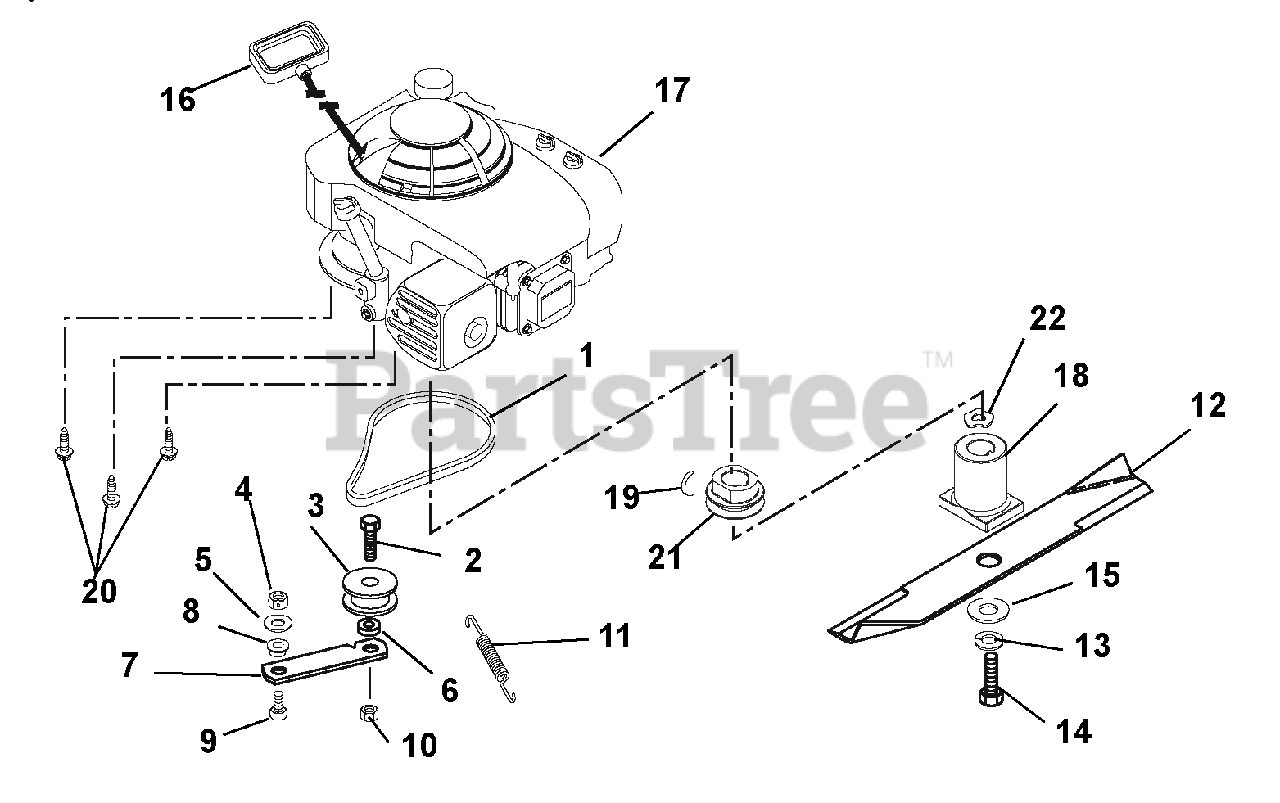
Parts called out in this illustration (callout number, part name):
1	V-BELT, 3L-COGGED
2	@BLT-HEX .44-14X1.50 GR5 YWZC
3	IDLER-FLAT 1.75 X .47
4	@NUT-LK-CTR .31-18 YWZC
5	@WSHR-FL-STL.344X.688X.065YWZC
6	BSHG-SLV .469 X .750 X .430
7	IDLER ARM
8	BSHG-FLG .325X.501X.250X1.120
9	@BLT-HEX .31-18X.75 GR5 YWZC
10	@NUT-LK-CTR .44-14 YWZC
11	SG-TENS .043X.44X3.31 WLD 5.8
12	21" MOWER BLADE
13	@WSHR-LK .38X.094 REG YWZC
14	BLT-HEX .38-24 X 2.00 GR8 YWZC
15	WSHR-FL-STL .390X1.5X.125 YWZC
16	HANDLE, RECOIL START
17	ENGINE, KAWASAKI 6.0 CONSUMER
18	ADAPTER-SINTERED IRON LM
19	KEY-WDRF .156X.625X.25 SAE 6
20	@SCR-TAP .38-16X1.00 HWH TR YZ
21	PULLEY-SINTERED IRON LM
22	WASHER-WAVE .885X1.311X.125
